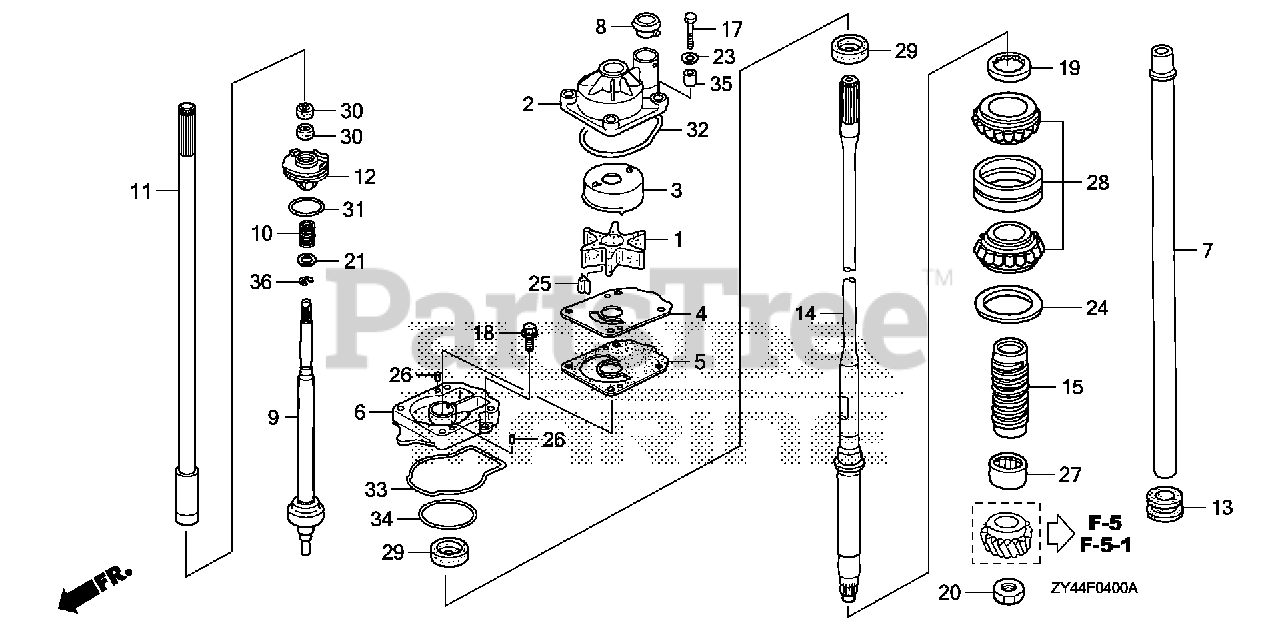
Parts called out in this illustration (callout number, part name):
1	IMPELLER, PUMP
2	HOUSING, IMPELLER
3	LINER, PUMP
4	COVER, IMPELLER
5	GASKET B, IMPELLER
6	HOUSING, WATER PUMP
7	TUBE, WATER (XXL)
8	RING, WATER TUBE SEAL
9	ROD, SHIFT
10	SPRING, SHIFT ROD
11	ROD A, SHIFT (XXL)
12	HOLDER, SHIFT ROD
13	GROMMET, EXTENSION CASE
14	SHAFT, VERTICAL (XXL)
15	SLINGER, OIL
17	BOLT, HEX. (8X60)
18	BOLT, FLANGE (6X16) (SUS)
19	NUT, LOCK (64MM)
20	NUT, HEX. (18MM)
21	WASHER, PLAIN (12MM)
23	WASHER (8MM)
24	SHIM A, GEAR (0.10)
24	SHIM B, GEAR (0.15)
24	SHIM C, GEAR (0.30)
24	SHIM D, GEAR (0.50)
25	KEY, WOODRUFF
26	PIN, DOWEL (6X10)
27	BEARING, NEEDLE (32X46X37)
28	BEARING, TAPER ROLLER (30X62X40)
29	SEAL, WATER (26X42X7)
30	SEAL, WATER (12X21X6)
32	O-RING, WATER PUMP
33	O-RING, WATER PUMP HOUSING
34	O-RING (69.1X2.4)
35	COLLAR, DISTANCE
36	E-RING (10MM)
